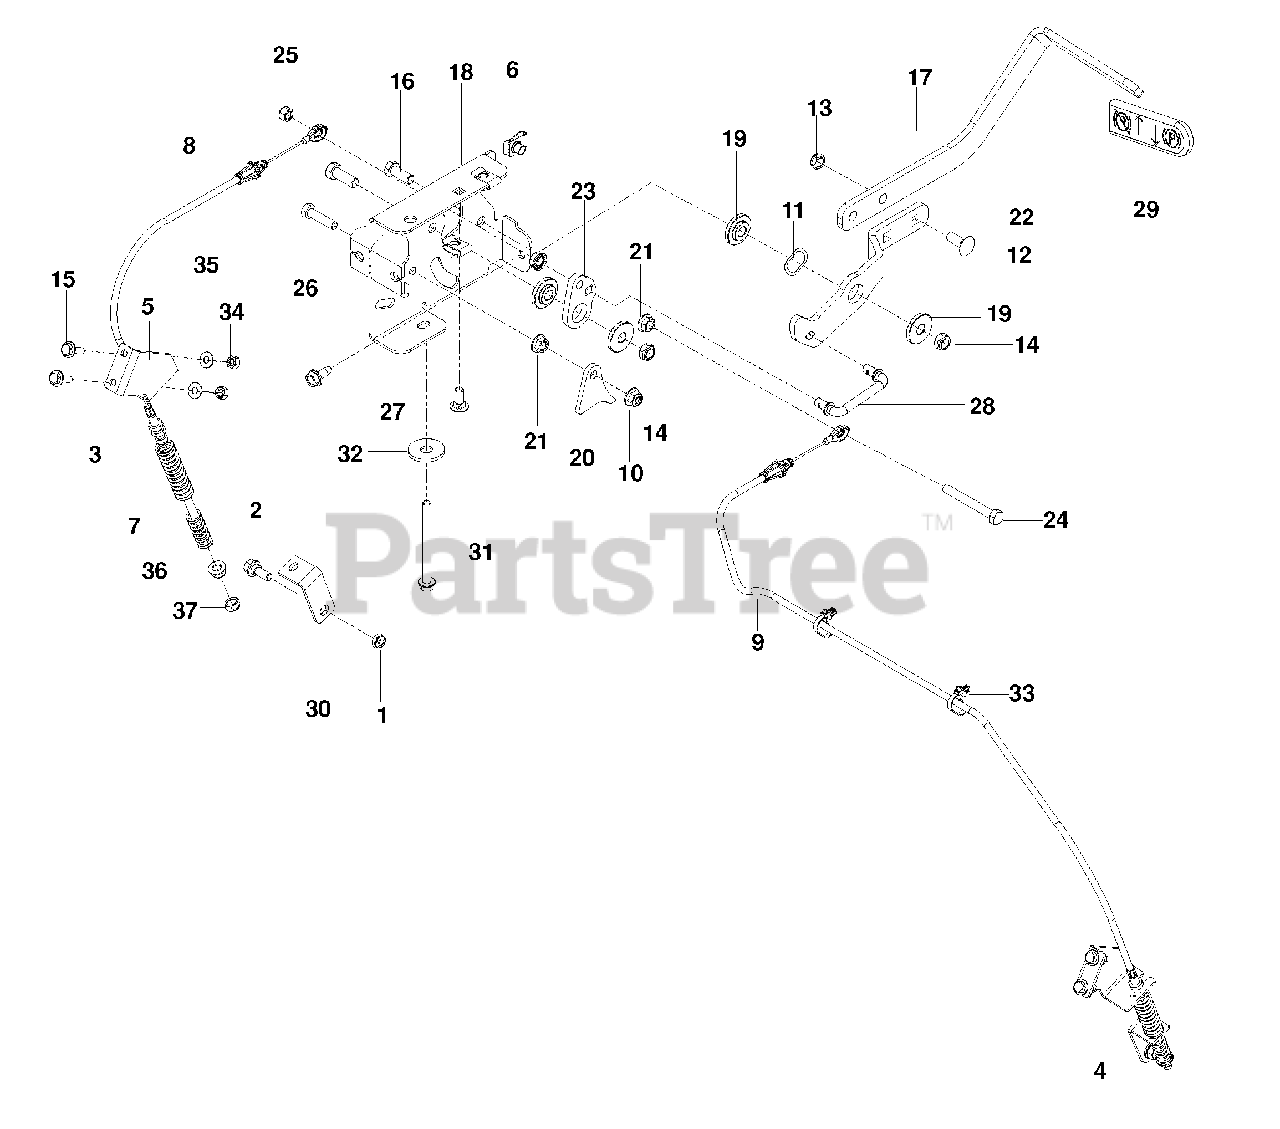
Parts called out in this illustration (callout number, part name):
1	NUT 5/16 HEX NYLOC
2	BOLT 5/16 SHOLDER
3	SPRING, RETURN
4	BRACKET, RT
5	BRACKET, LT
6	RETAINER, U TYPE 5/16-18
7	SPRING, ENGAGEMENT
8	CABLE, BRAKE, SHORT
9	CABLE, BRAKE, LONG
10	NUT 5/16-18 FLANGE NYLOC
11	WASHER .825 WAVE
12	BOLT, RD HD 3/8-16 x 1
13	NUT 3/8-16 HEX FLG NYLOC
14	NUT 3/8-16 HEX JAM NYLOC
15	HCS 1/4-20 x 7/8
16	BOLT, HEX 3/8-16 x 1
17	ARM, BRAKE
18	MOUNT, BRAKE
19	BUSHING, BRAKE
20	ACTUATOR, SWITCH
21	NUT 5/16-18 HEX WHIZLK
22	LEVER, BRAKE
23	BELLCRANK, BRAKE
24	BOLT, HEX 5/16-18 x 2 1/2 TPBLT
25	NUT 5/16-18 HEX NYLOC
26	BOLT, HEX 5/16-18 x 1
27	BOLT, RD HD 5/16-18 x 3/4
28	LINKAGE, BRAKE
29	GRIP, BRAKE HANDLE
30	BRACKET, BRAKE
31	HHFS 5/16-18 x 3 3/4
32	WASHER 1/2 FLAT
33	TIE, w/ CLIP
34	NUT 1/4-20 HEX NYLOC
35	WASHER 1/4 FLAT SAE
36	NUT 5/16-18, WHIZLK
37	NUT 5/16-18, JAM
